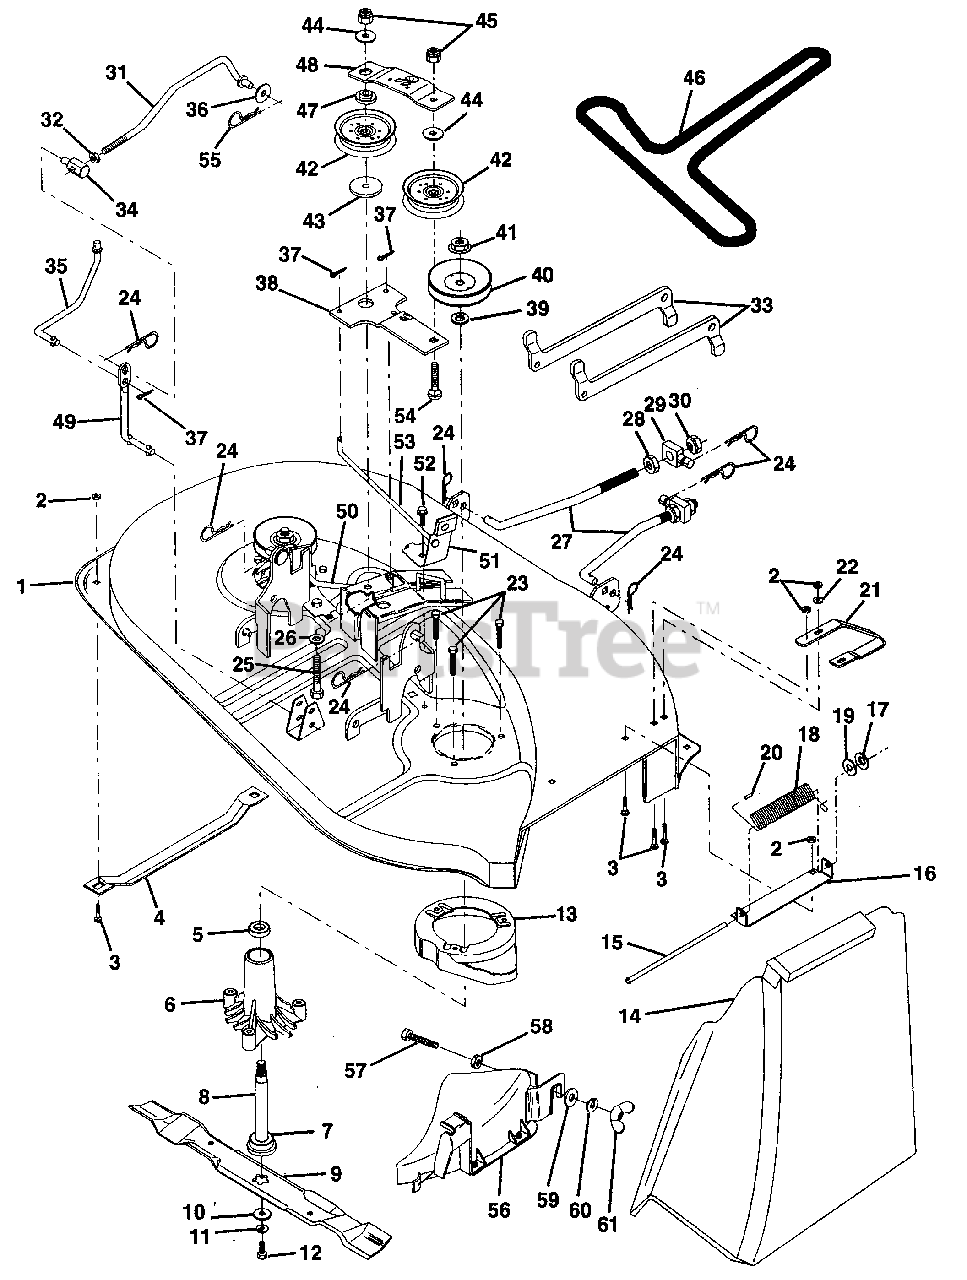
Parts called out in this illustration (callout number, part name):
1	Mower Deck Assembly (AYP part number)
2	Nut, Crownlock 5/16-18
3	Bolt, Carriage 5/16-18 x 3/4
4	Runner, LH (AYP part number)
5	Bearing (AYP part number)
6	Housing, Mandrel
7	Bearing (AYP part number)
8	Shaft & Bearing Assembly, Mandrel (Includes Key Number 7)
9	Blade, Mulching
10	Washer, Hardened (AYP part number)
11	Washer, Lock 3/8 (AYP part number)
12	Bolt 3/8-24 x 1-1/4 Grade 8 (AYP part number)
13	Stripper, Mower, Vented (AYP part number)
14	Shield, Deflector (AYP part number)
15	Rod, Hinge (AYP part number)
16	Bracket Assembly, Deflector (AYP part number)
17	Pushnut (AYP part number)
18	Spring, Deflector (AYP part number)
19	Washer 11/32 x 5/8 x 16 Gauge (AYP part number)
20	Cap, Sleeve (AYP part number)
21	Runner, RH (AYP part number)
22	Washer 11/32 x 3/4 x 16 Gauge (AYP part number)
23	Bolt 5/16-18 x 1-1/4 (AYP part number)
24	Retainer, Spring (AYP part number)
25	Bolt, Carriage 3/8-16 x 2-1/4 (AYP part number)
26	Washer 13/32 x 1 x 12 Gauge (AYP part number)
27	Link Assembly, Front (AYP part number)
28	Nut, Hex, Jam 1/2-13 UNC (AYP part number)
29	Trunnion (AYP part number)
30	Locknut with Washer Insert 1/2-13 UNC (AYP part number)
31	Rod, Clutch, Primary (AYP part number)
32	Nut, Hex, Jam 3/8-16 (AYP part number)
33	Arm, Suspension, Rear (AYP part number)
34	Trunnion 3/8-16 (AYP part number)
35	Rod, Clutch, Secondary (AYP part number)
36	Washer 13/32 x 13/16 x 16 Gauge (AYP part number)
37	Pin, Cotter 3/32 x 3/4 (AYP part number)
38	Idler Arm (AYP part number)
39	Washer .150 Thick (AYP part number)
40	Pulley, Mandrel (AYP part number)
41	Nut, Flangelock 9/16 (AYP part number)
42	Pulley, Idler, Flat (AYP part number)
43	Spacer, Retainer (AYP part number)
44	Washer 13/32 x 1 x 12 Gauge (AYP part number)
45	Nut, Crownlock 3/8-16
46	Belt (AYP part number)
47	Spacer, Idler Arm (AYP part number)
48	Stiffener, Idler Arm (AYP part number)
49	Rod, Pivot (AYP part number)
50	Rod, Brake, LH (AYP part number)
51	Brake Assembly (AYP part number)
52	Screw, Hex Washer Head, Thd., Roll. 5/16-18 x 3/4
53	Rod, Brake, RH (AYP part number)
54	Bolt, Carriage 3/8-16 x 1-3/4 Grade 5 (AYP part number)
55	Spring, Retainer (AYP part number)
56	Cover, Mulcher (AYP part number)
57	Bolt, Hex 3/8-16 x 1-1/4 (AYP part number)
58	Locknut 3/8-16 (AYP part number)
59	Washer 13/32 x 1-1/4 x 16 Gauge (AYP part number)
60	Washer, Lock 3/8 (AYP part number)
61	Wing Nut (AYP part number)
